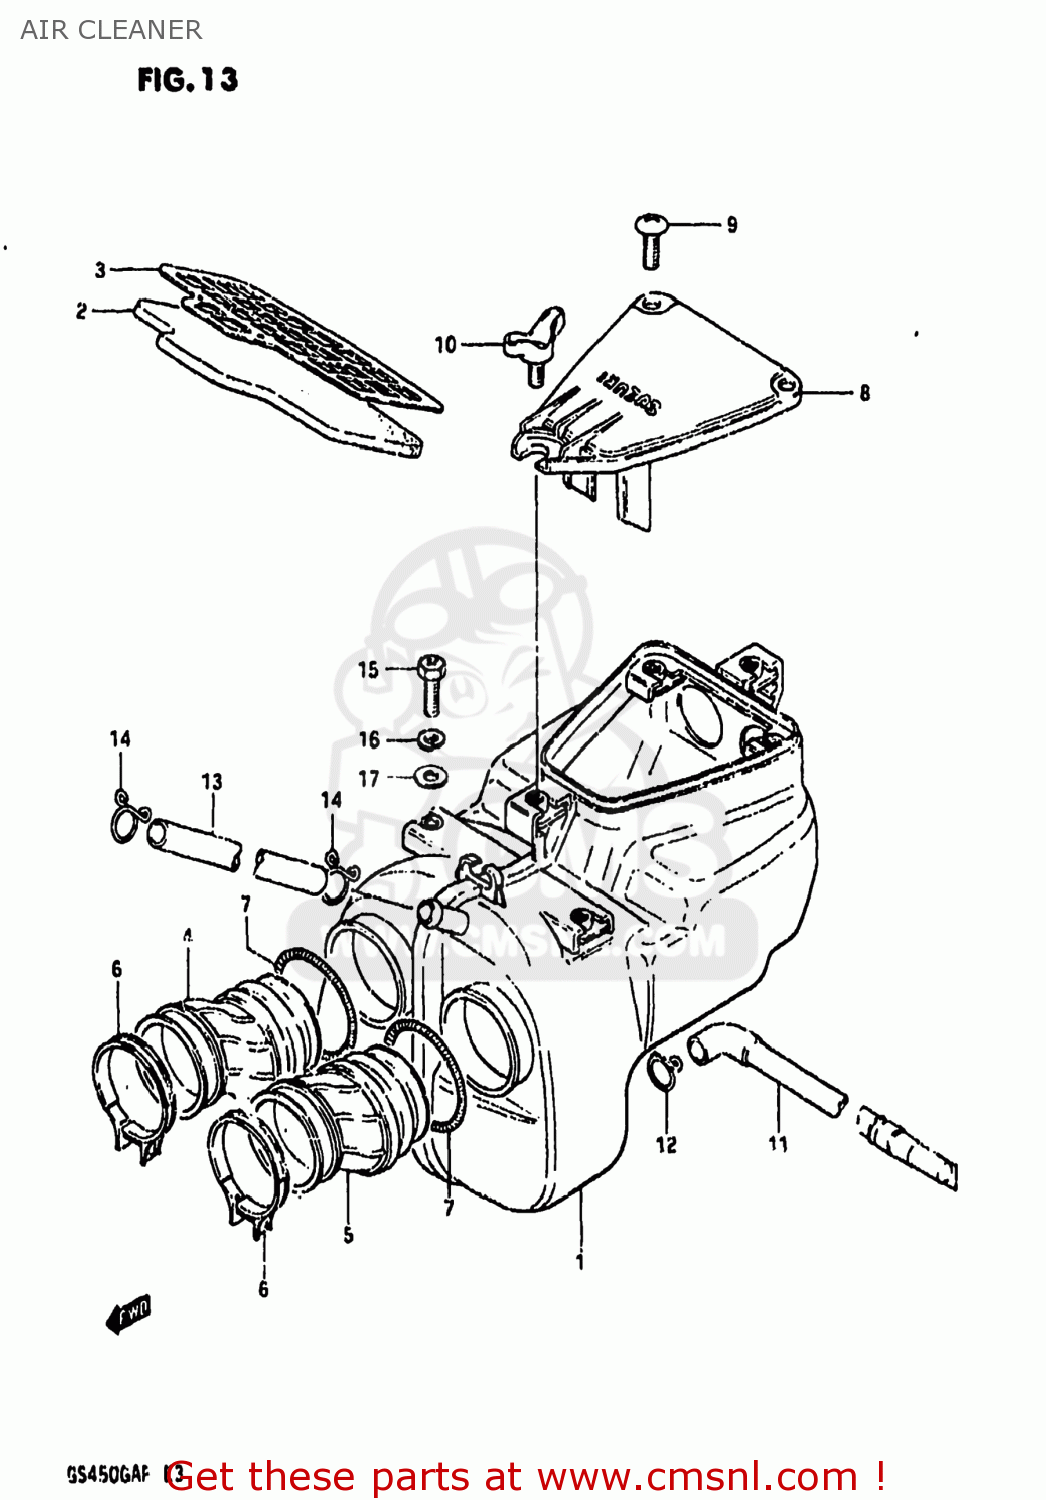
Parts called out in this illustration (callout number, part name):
1	CLEANER ASSEMBLY,AIR
2	FILTER
3	HOLDER,OUTER
4	TUBE,OUTLET,R
5	TUBE,OUTLET,L
6	CLAMP
7	CLAMP,CLEANER SIDE
8	CAP,AIR CLEANER
9	SCREW
10	BOLT, WING
11	DRAIN TUBE
12	CLIP
13	TUBE,BREATHER
14	CLAMP
15	SCREW(6X12)
16	LOCK WASHER
17	WASHER
